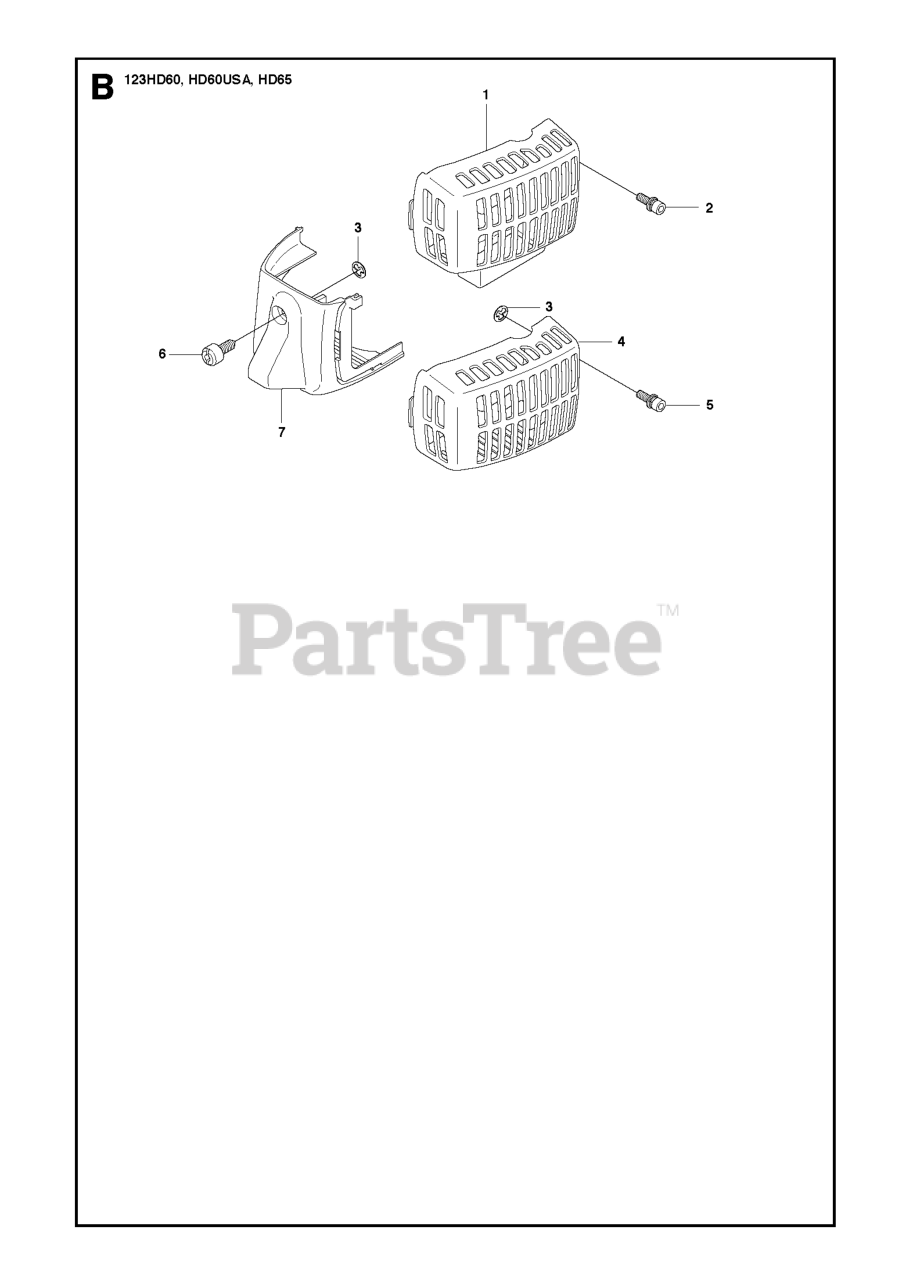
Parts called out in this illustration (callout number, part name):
1	HEAT SHIELD
4	MUFFLER COVER
7	CYLINDER COVER
